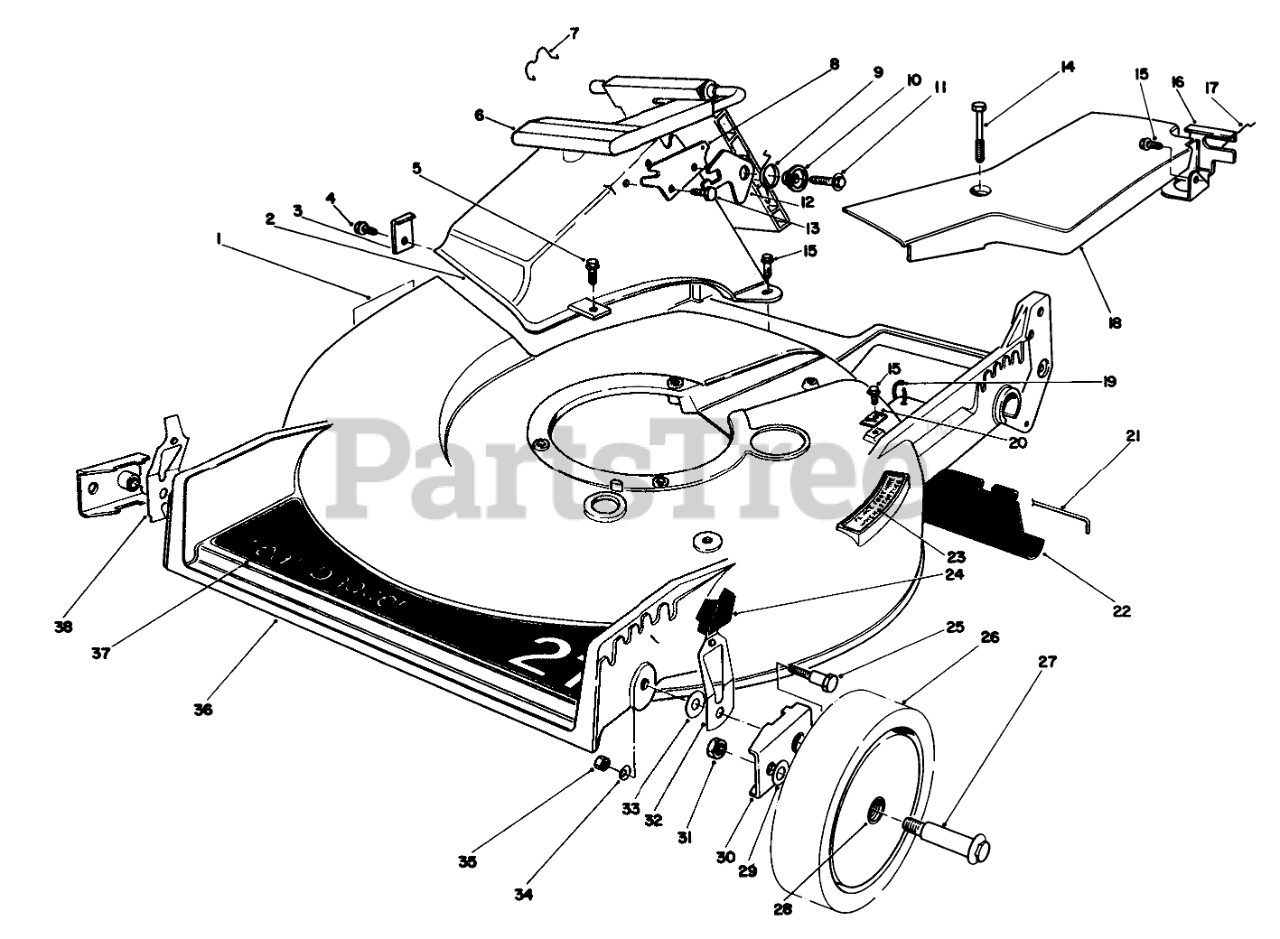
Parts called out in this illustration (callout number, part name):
1	DECAL-DANGER
2	Tunnel Discharge
3	TUNNEL CLIP
4	SCREW
5	SCREW-HWH
6	Discharge Door Assembly
7	DOOR RET SPRING
8	DOOR LATCH PLATE
9	TORSION SPRING
10	DOOR SPACER
11	SCREW-HWH
12	SAFETY LATCH
13	SCREW-PLASTITE
14	SCREW-HHFTF
15	SCREW-HWHTF
16	Bracket-Traction Adj.
17	RETAINER-CABLE
18	Belt Cover
19	TIE-CABLE
20	Cable Clamp
20	CLAMP-CABLE
21	ROD-SHIELD
22	SHIELD-TRAILING
23	STEP PAD DECAL
24	KNOB-ARM
25	PIVOT SCREW
26	Wheel & Tire (Incl. Ref. #17)
27	BOLT-WHEEL
28	BUSHING
29	WASHER
30	HP PIVOT ARM ASM
31	Nut
32	L. HP SPRING ARM ASM
33	WASHER-PIVOT
34	WASHER-BELLEVILLE
35	NUT-LOCK, NI
36	Housing
37	DECK DECAL
38	R HP SPRING ARM ASM
